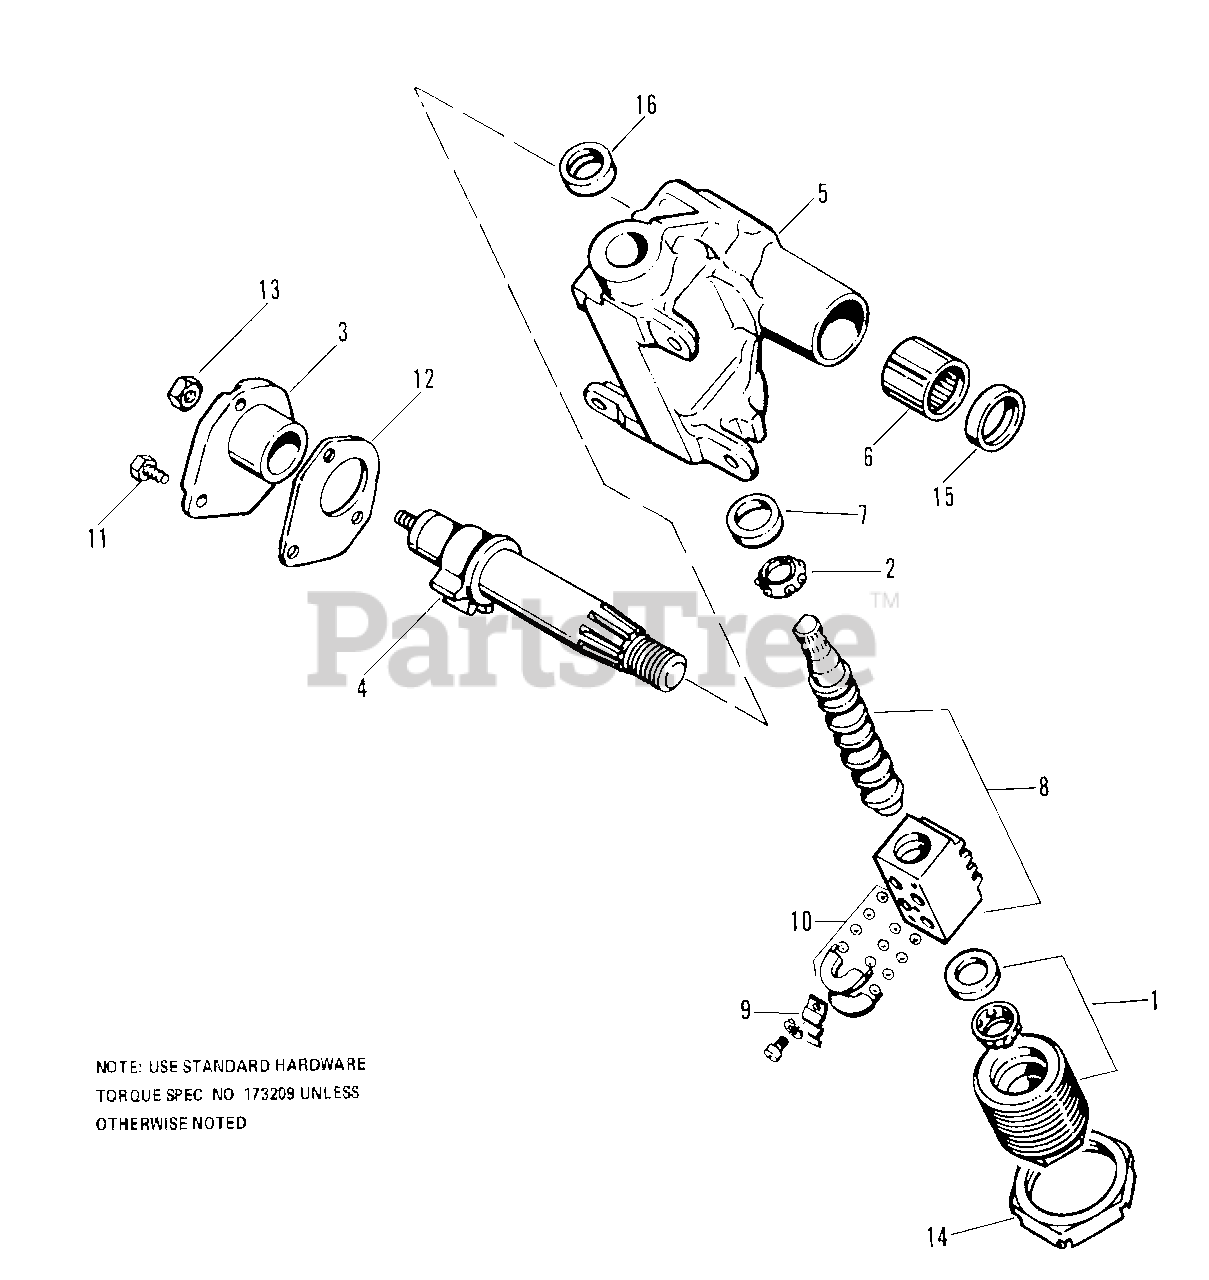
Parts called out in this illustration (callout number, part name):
1	BEARING ASSY, Adj. Worm
2	BEARING ASSY, Worm
3	COVER ASSY
4	GEAR ASSY, Pitman
5	HOUSING ASSY
6	BEARING, Needle
7	CUP, Bearing Thrust
8	WORM ASSY
9	CLAMP, Ball Return
10	GUIDE, Ball Return
11	BOLT, Hex
15	SEAL, Grease
